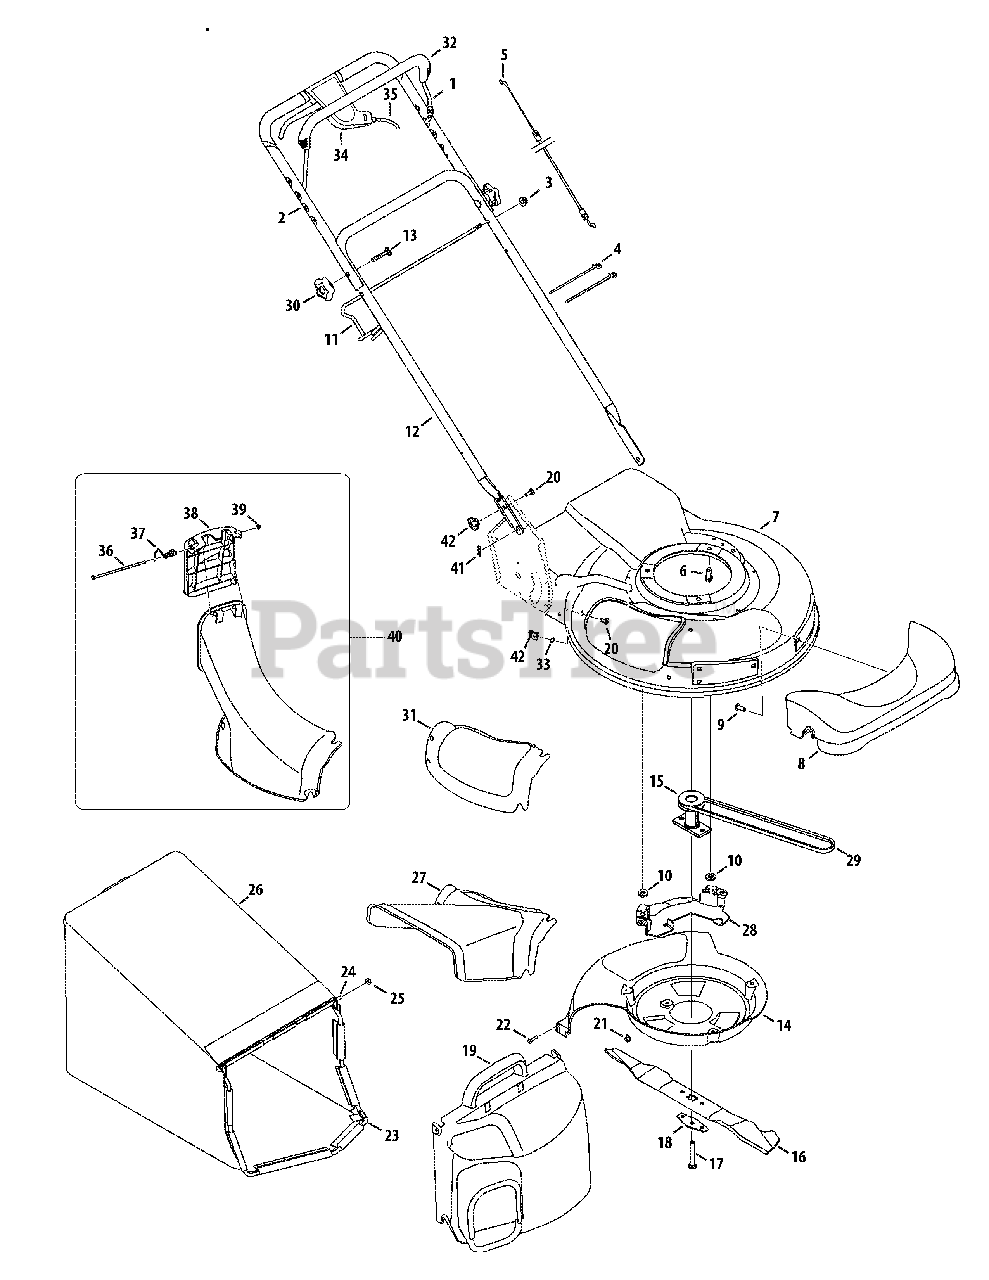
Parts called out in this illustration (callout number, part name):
1	Blade Control
2	Upper Handle
3	Flange Lock Nut, 5/16-18
4	Cable Tie
5	Control Cable
6	TT Screw, 3/8-16 x 1.00
7	21-inch Deck
8	Front Axle Cover
9	HL Screw, 5/16-14 x .750
10	Washer, Flat, .407 x .812 x .135
11	Grass Bag Support Rod
13	Carriage Bolt 5/16-18 x 2
14	Rear Baffle
15	Blade Adapter
16	21-inch Mulching Blade
17	HH Cap Screw, 3/8-24 x 2.50
18	Bell Blade Spacer
19	Grass Bag Cover Assembly
20	Carriage Screw 1/4-20 x .75
21	TT Screw 1/4-20 x .375
22	HL Screw 1/4-15 x .75
23	Grass Bag Frame
24	Grass Bag Pivot Rod
25	Cap Speed Nut
26	Grass Bag Assembly
27	Side Discharge Chute
28	Belt Keeper
29	V-Belt
30	Star Knob
31	Mulch Cover
32	Bail Cover
33	Push Nut
34	Drive Control Assembly
35	Drive Cable
36	Chute Door Pivot Rod
37	Torsion Spring
38	Top Discharge Door Chute
39	Push Cap
40	Top Discharge Chute Assembly
41	Cotter Pin
42	Wing Nut
